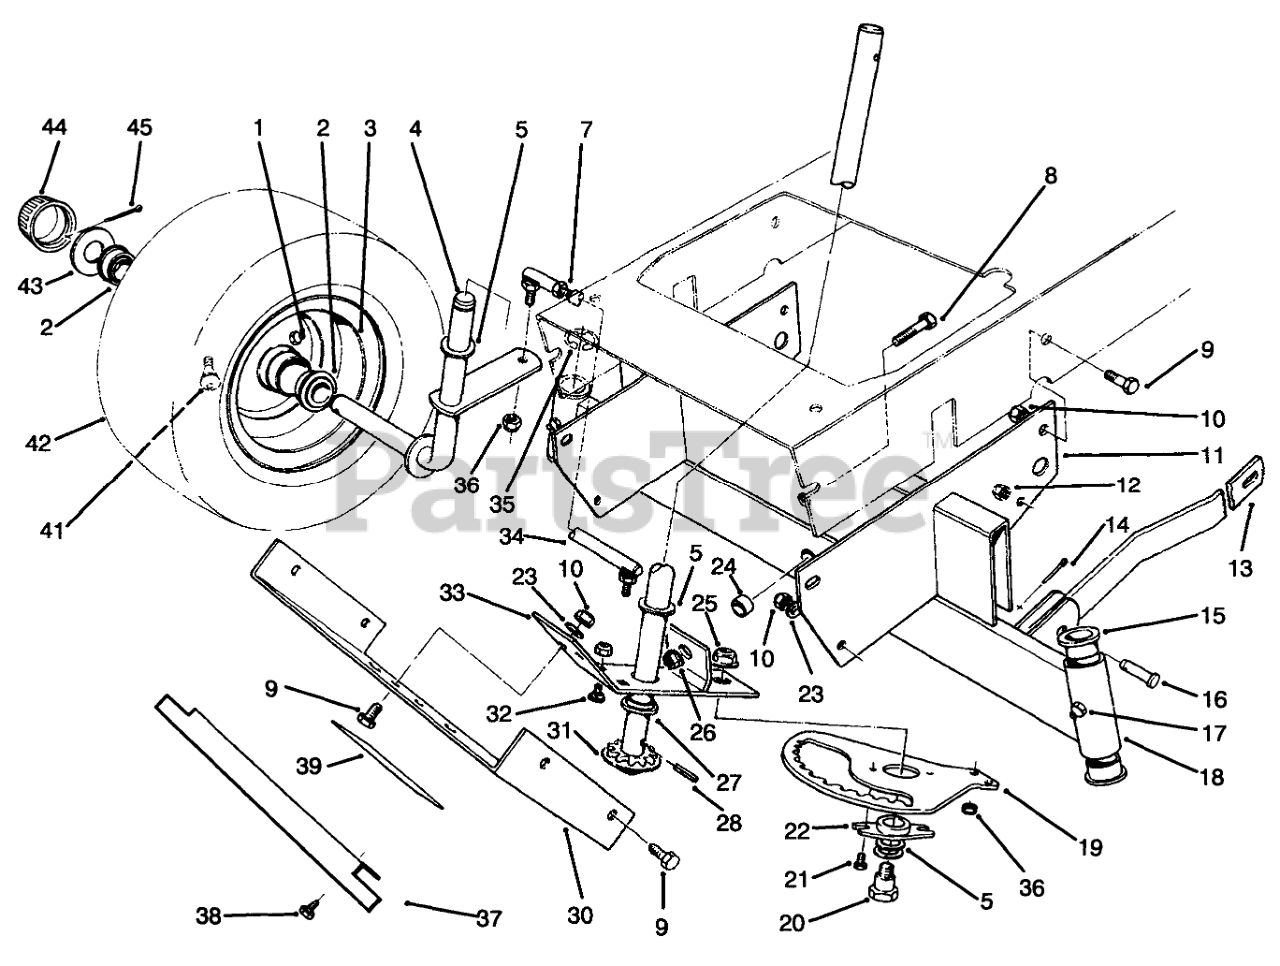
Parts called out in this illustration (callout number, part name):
1	FITTING-GREASE
2	Bearing
4	Spindle RH
5	WASHER-THRUST
7	NUT-JAM
8	SCREW-HH
9	SCREW-HH
10	NUT-LOCK, NI
11	Support
12	NUT-HEX
13	Arm-Suspension, Front
14	PIN-COTTER
15	BEARING-FLANGE
16	PIN-CLEVIS
17	GREASE FITTING
18	Axle-Front (Incl. Ref. #15 & 17)
19	Rack-Steering
21	SCREW-HWH
22	BUSHING-SECTOR
23	WASHER-PLAIN
24	SPACER-AXLE, FRONT
25	NUT-HF
26	NUT-HF
27	BEARING-FLANGE
28	PIN-ROLL, SLOTTED
30	Cover-Front
31	STRG SHAFT WA
32	SCREW-CARR
33	Bracket-Rack, Steering (Incl. Ref. #27)
34	Tie Rod-Adjustable (Incl. Ref. #7)
35	E-RING
36	NUT-LOCK
37	Guard-Front
38	SCREW-HWHTF
39	DECAL - IMPORTANT
41	Stem-Valve
42	TIRE,PNEU.11X4.00X5
43	WASHER-PLAIN
44	CAP-HUB
45	PIN-COTTER
